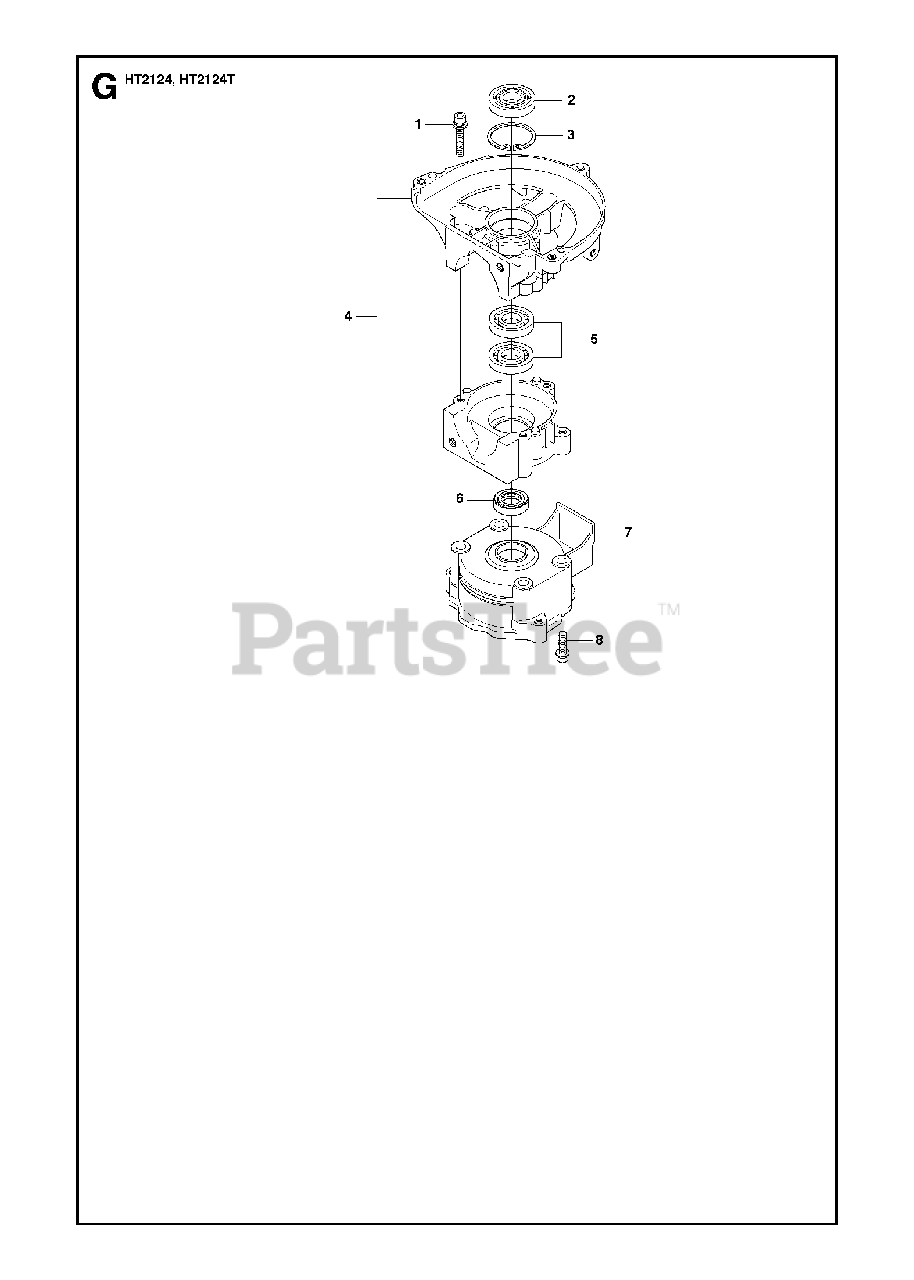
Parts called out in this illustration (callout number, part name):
2	SEALING RING
4	CRANKCASE COMPLETE
5	BALL BEARING
6	SEALING RING
7	CLUTCH COVER
